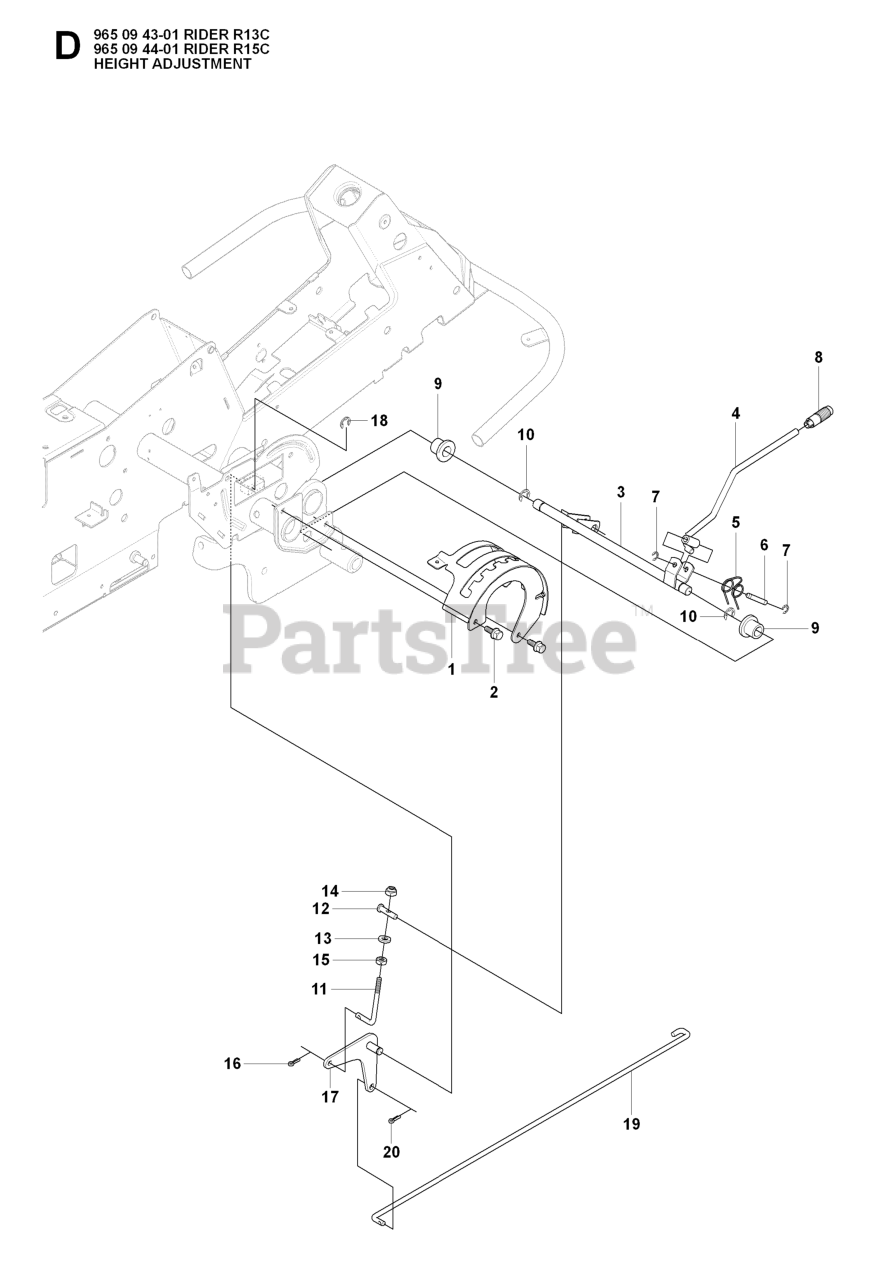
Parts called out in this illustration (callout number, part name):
1	CONTROL PLATE
3	HEIGHT ADJUSTER
4	HEIGHT ADJUSTER
5	HAIR PIN SPRING
8	GEAR STICK KNOB
9	BUSHING
13	WASHER
14	LOCKNUT M8
15	NUT
17	LINK HEIGHT ADJUSTMENT
18	RETAINING RING
19	CONNECTION ROD
